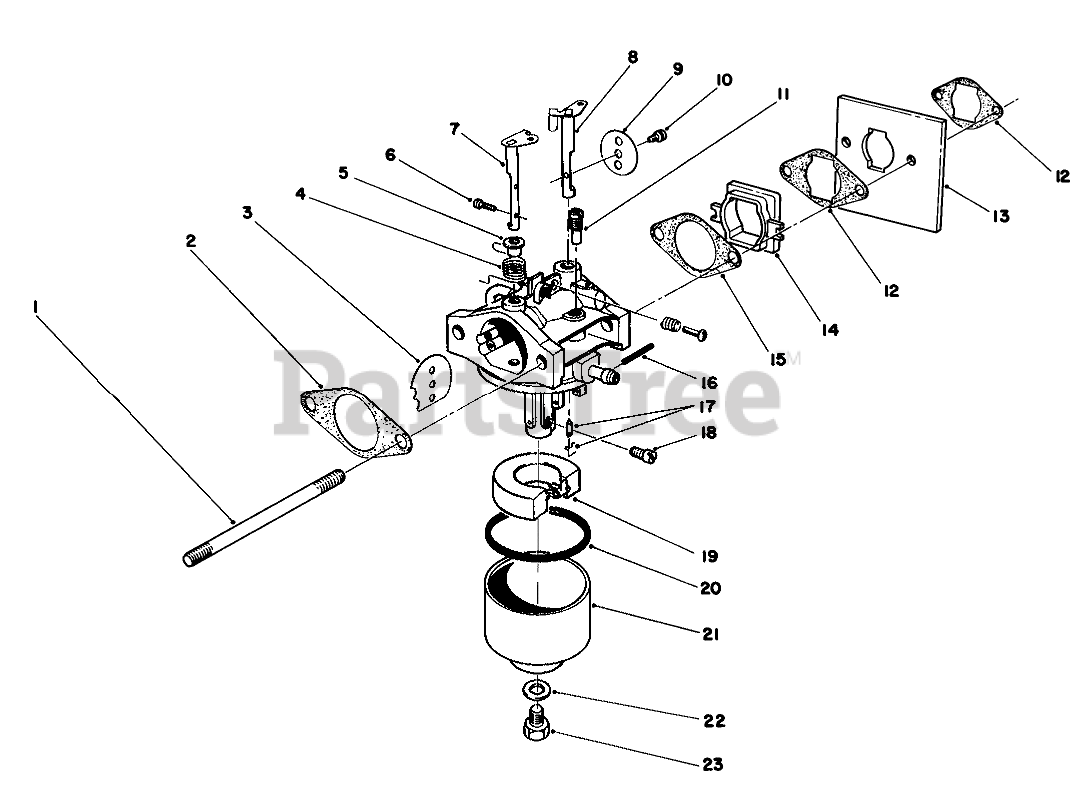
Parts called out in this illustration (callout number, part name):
1	CARB STUD BOLT
2	GASKET-AIR CLEANER
3	PLATE
4	SPRING
5	BUSHING
6	SCREW
7	SHAFT-CHOKE
8	SHAFT
9	PLATE
10	Screw-Throttle
11	PILOT JET
12	GASKET
13	SHIELD
14	INSULATOR
15	GASKET-CARB
16	Pin
17	NEEDLE VALVE ASM
18	MAIN JET (76.3)
19	FLOAT
20	GASKET
21	Bowl-Float
22	GASKET
23	Bolt
